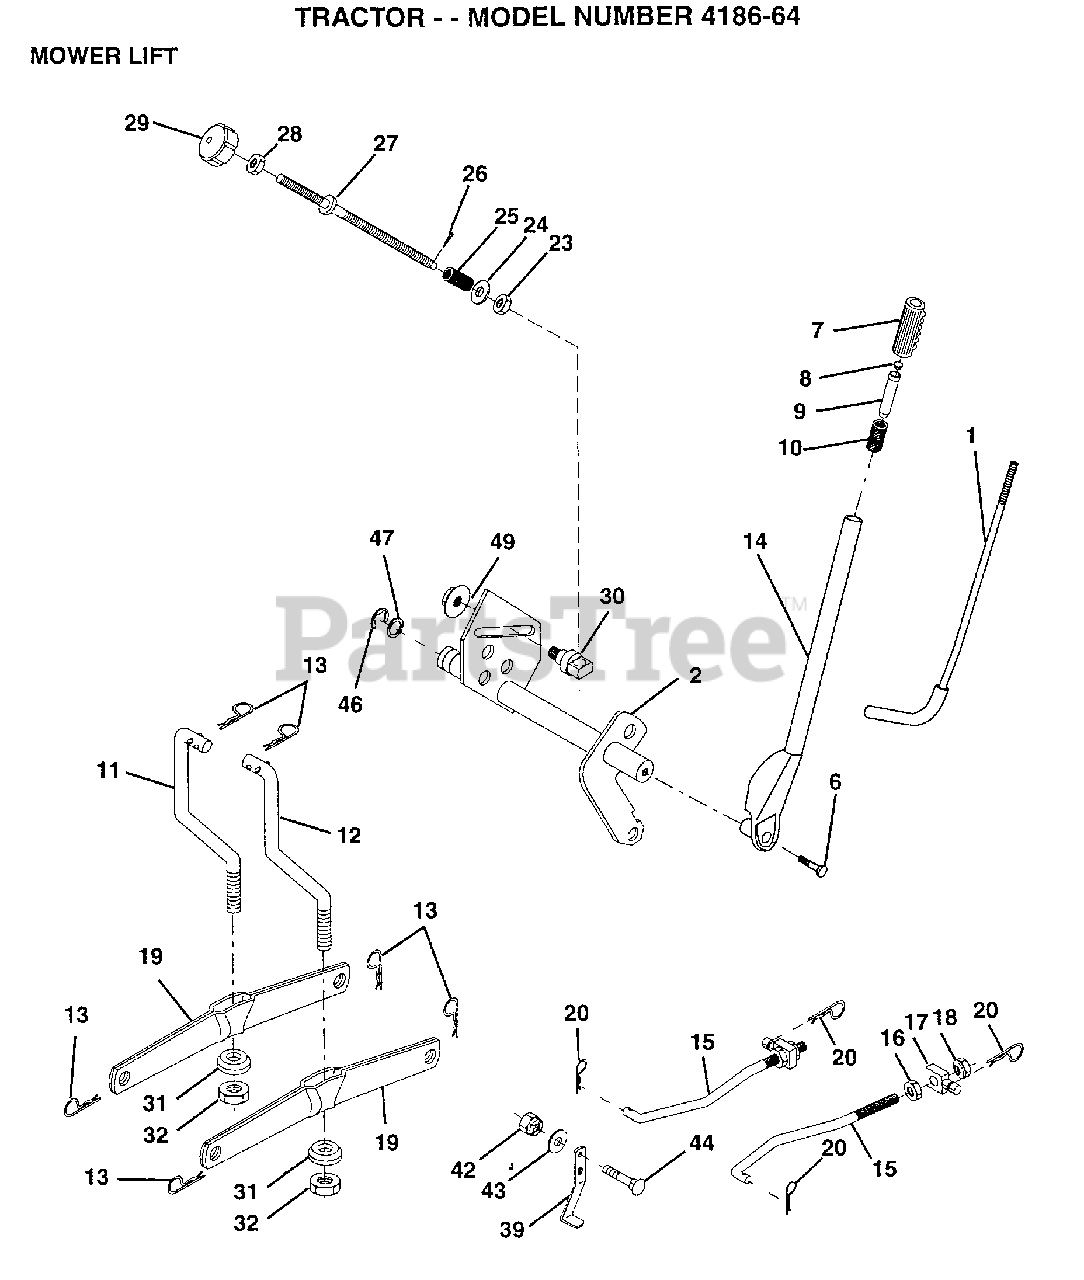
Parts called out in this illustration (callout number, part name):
1	LEVER ROD LT
2	SHAFT LIFT W/IND
6	"BOLT,HEX"
7	GRIP
10	SPRING T
11	LINK.LIFT.LH.GTV
12	LINK.LIFT.RH.GTV.
15	LINK.FRONT
16	NUT
17	TRUNION
18	NUT.LK.W/WSH.1/2.
19	ARM SUSP REAR
20	RETAINER.SPRING
23	NUT T
24	WASHER
25	SPRING.COMP.INF.H
27	ROD.ADJ.LIFT
28	NUT
29	KNOB INF 3/8-16
30	TRUNNION
31	BEARING PVT LH
32	NUT.CROWNLOCK.3/8
39	STOP.OVER.CENTER
43	WASHER GT
44	BOLT
46	E-RING
47	WASHER
49	NUT.HXFLG.LOCK.
